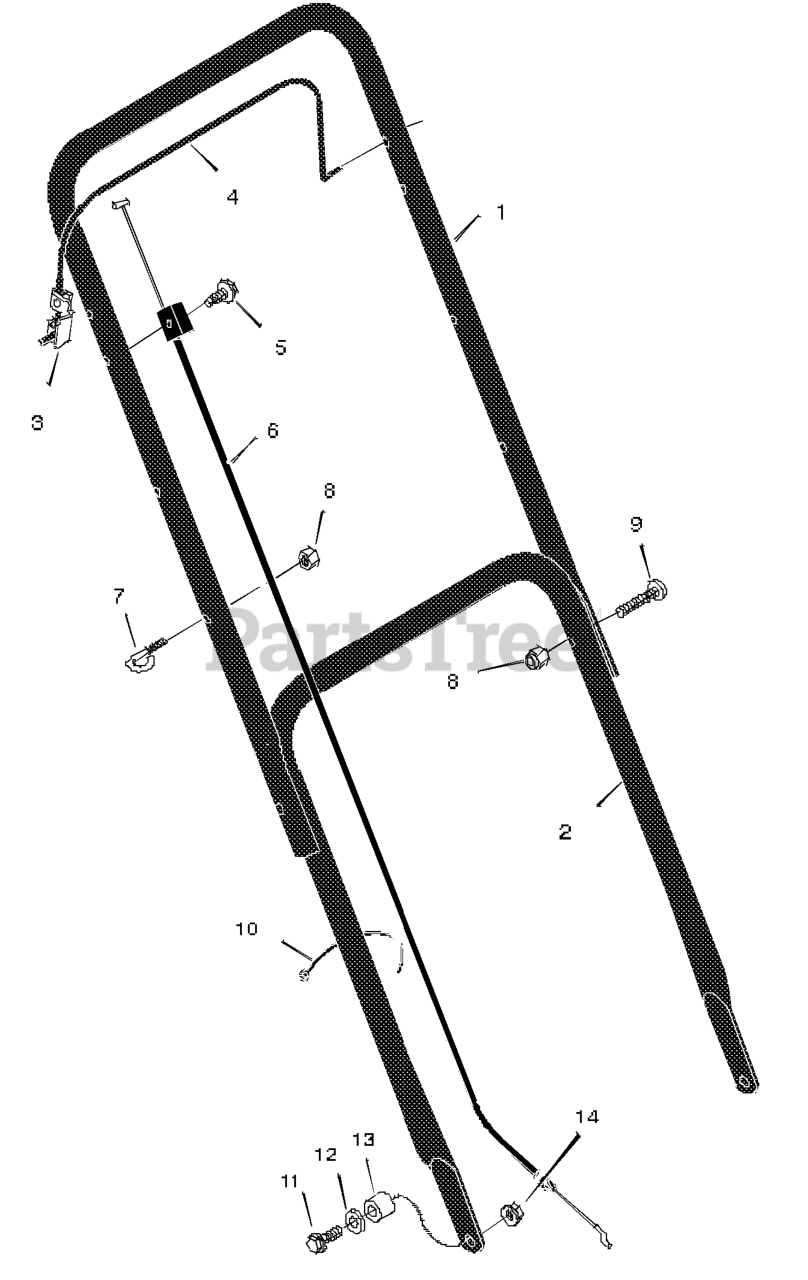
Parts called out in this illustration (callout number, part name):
1	Handle, Upper
2	Handle, Lower
3	Bracket, Stop Lever
4	Lever, Stop
6	Engine Stop Cable
7	GUIDE, ROPE
8	Locknut
10	Fastener, Cable
11	Bolt
14	Nut
